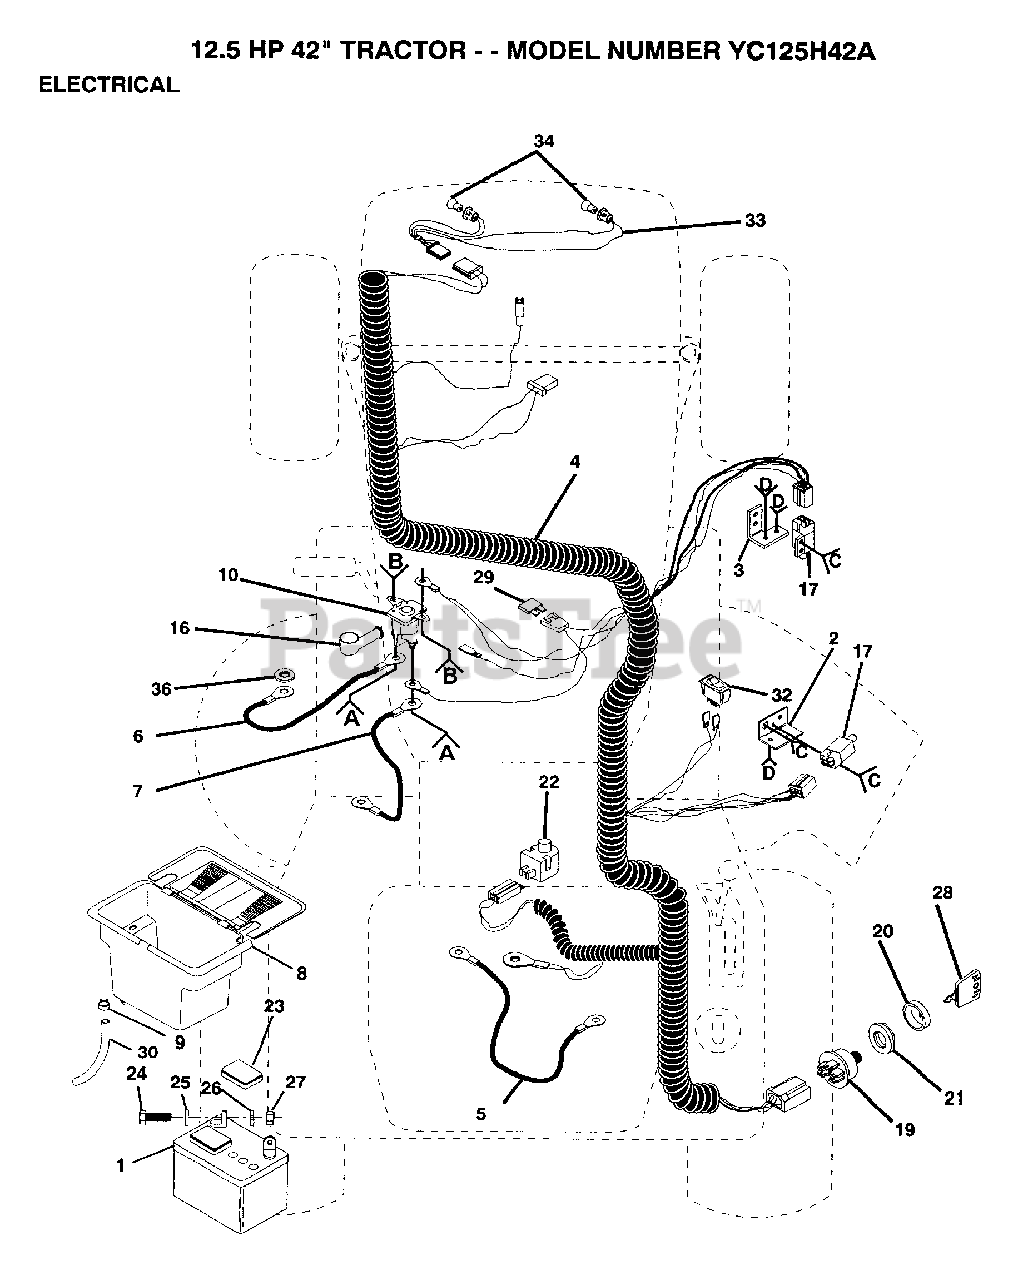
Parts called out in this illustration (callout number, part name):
2	SWITCH BRACKET
3	BRACKET LT
4	IGN HARNESS
5	CABLE T
7	"CABLE T, BATTERY"
9	HOSE CLAMP T
12	NUT
13	BOLT
15	NUT
17	SWITCH INTERLOCKT
18	SCREW
21	NUT IGNITION
22	SWITCH SEAT
23	"CAP,BATTERY "
24	BOLT LT
25	WASHER
26	LOCKWASHER
28	KEY
29	FUSE HYT
30	TUBE T
32	SWITCH LT
35	SCREW
36	LOCKWASHER
